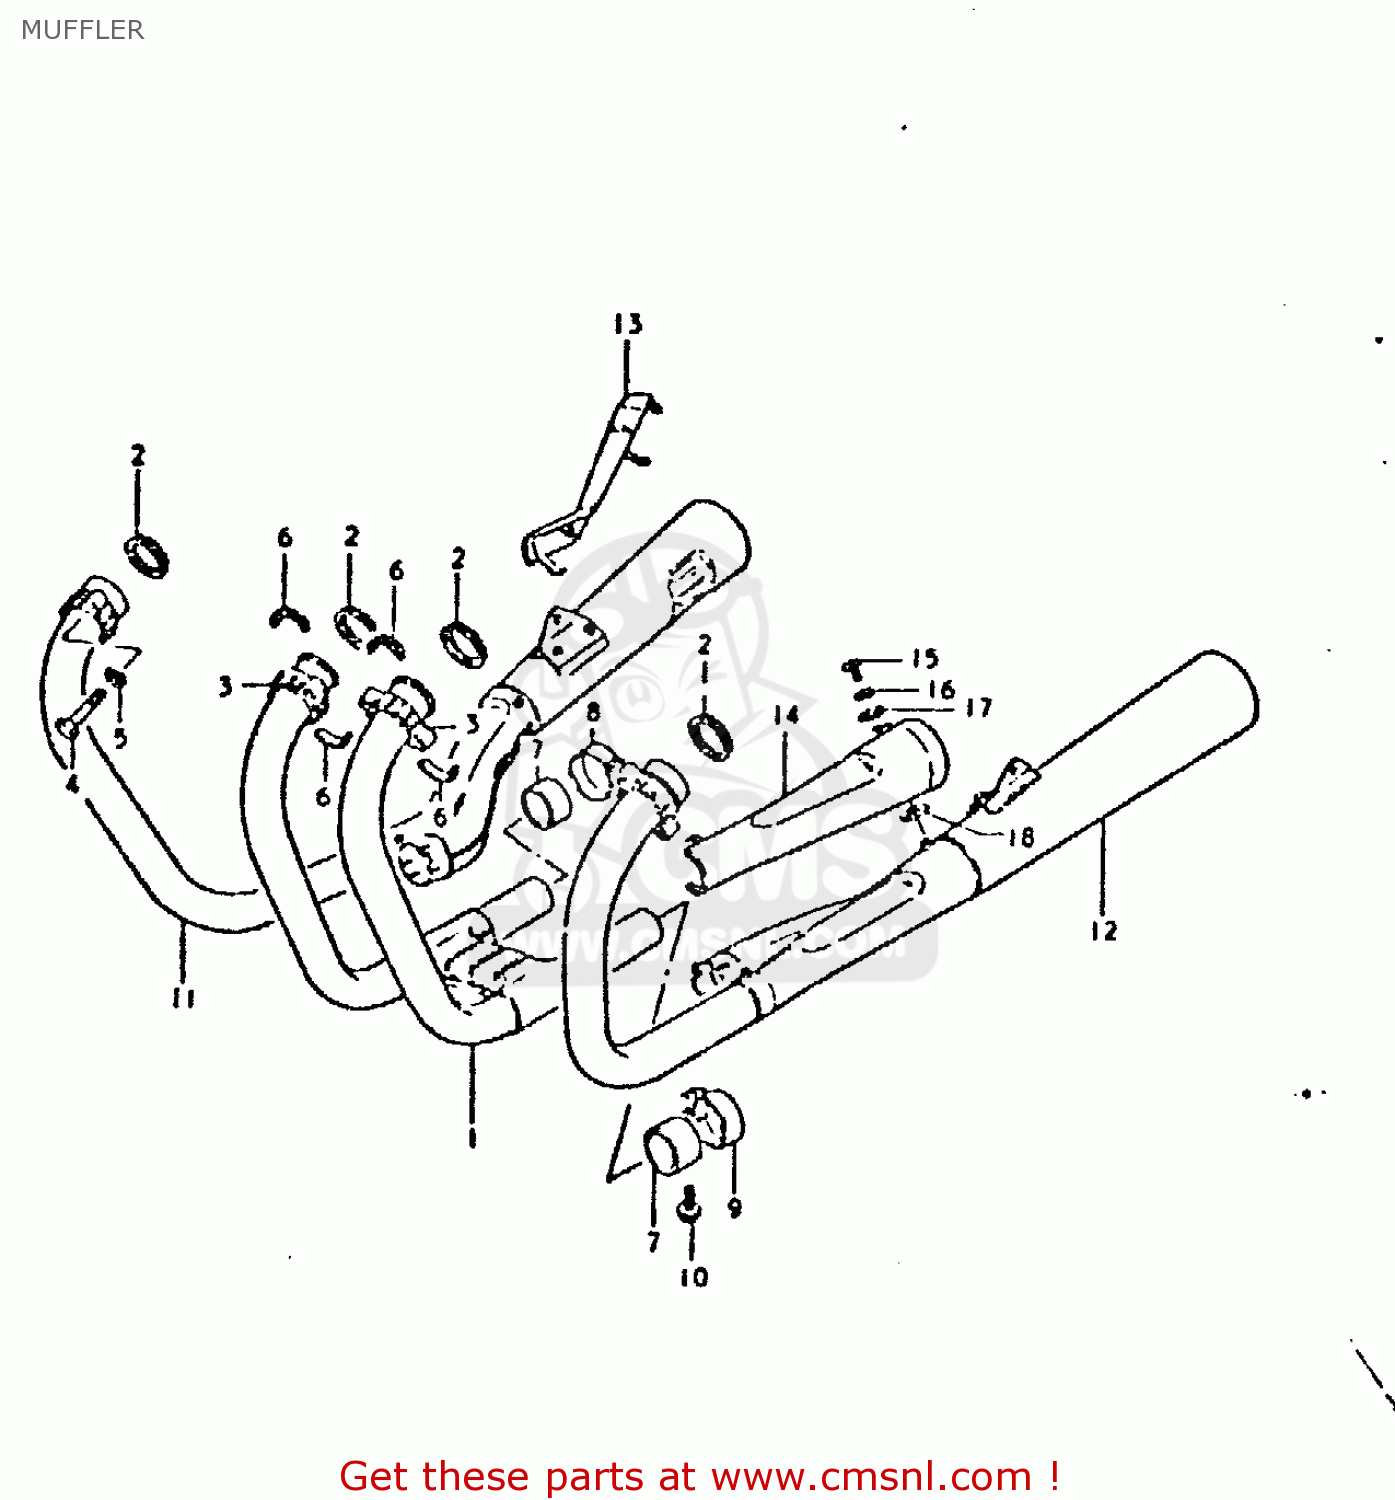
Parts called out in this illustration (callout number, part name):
1	PIPE,EXHAUST
2	GASKET,EXHAUST PIPE (NAS)
3	CLAMP,EXHAUST PIPE
4	BOLT
5	LOCK WASHER
6	PLATE,EXHAUST P
7	CONNECTOR,MUFFLER
8	CLAMP,MUFFLER CONNECTOR,R
9	CLAMP,MUFFLER CONNECTOR,L
10	BOLT
11	MUFFLER ASSEMBLY
12	MUFFLER ASSEMBLY
13	COVER,MUFFLER
14	COVER,MUFFLER
15	SCREW
16	LOCK WASHER
17	WASHER
18	GASKET 6.2X12X1.5 (MCA)
